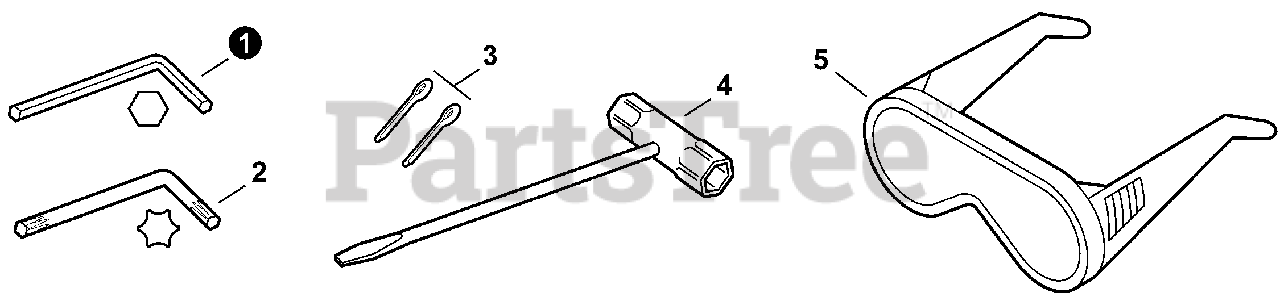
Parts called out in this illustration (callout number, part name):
1	WRENCH, ALLEN 4 MM
2	WRENCH, T27 80×30
3	PIN, COTTER 2×22
4	T-WRENCH 17x-19 L200
5	GLASSES, SAFETY
